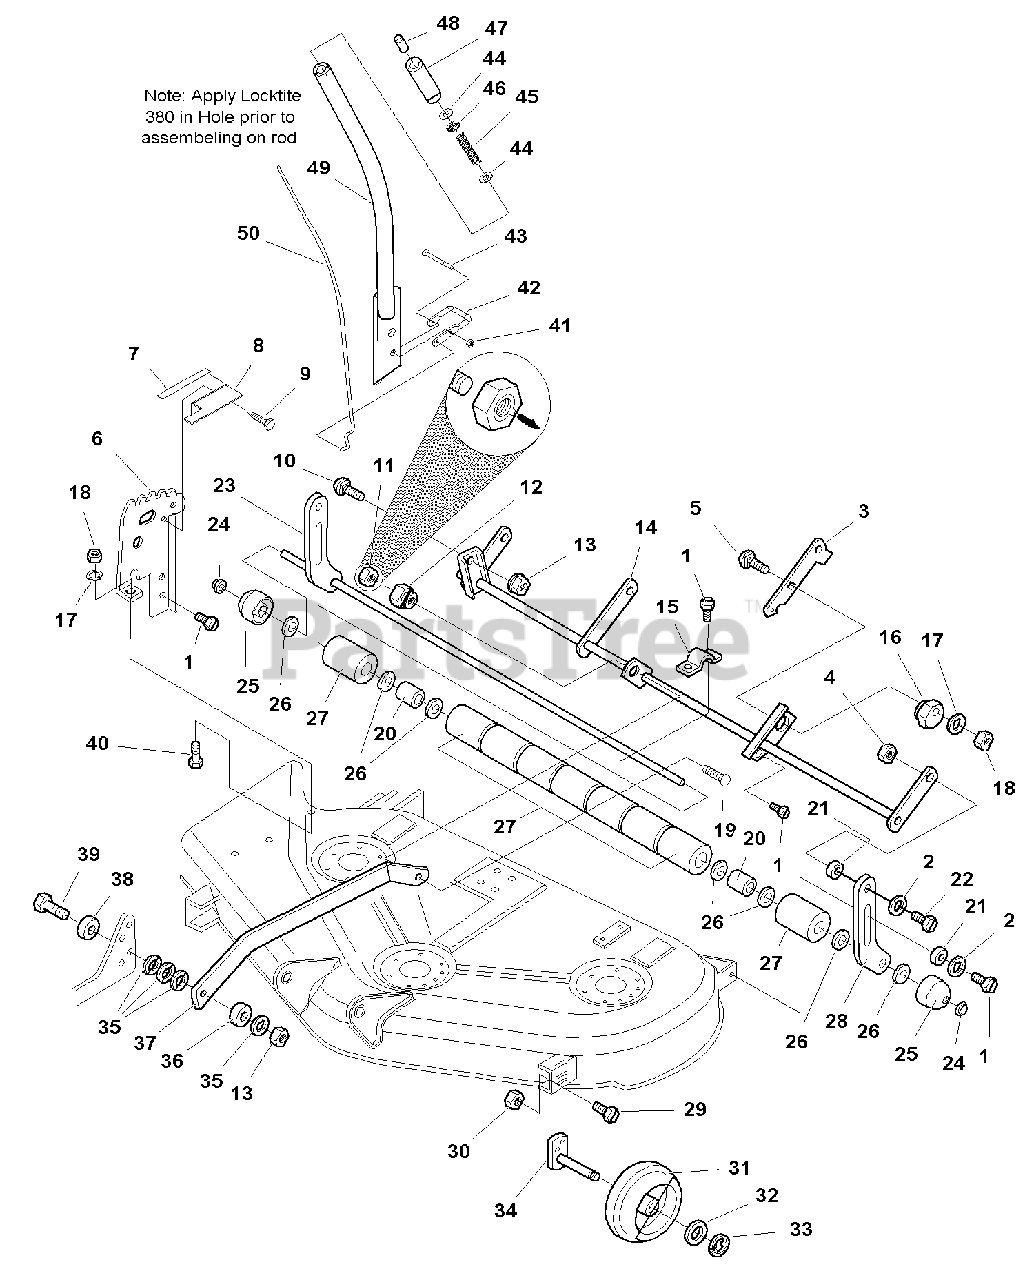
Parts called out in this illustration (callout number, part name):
1	CAPSCREW, Taptite Hex Washer Head, 5/16-18 x 1
2	WASHER, 5/16
3	ARM ASSEMBLY
4	NUT, Hex Lock, 5/16-18
5	CARRIAGE BOLT, 5/16-18 x 1-1/4
6	QUADRANT 44"
7	DECAL, Height of Cut
8	BRACKET, Decal
9	CAPSCREW, Hex Head, Taptite, 5/16-18 x 1/2
10	CARRIAGE BOLT, 3/8-16 x 1
11	* NUT, Hex Lock, Alum Insert, 3/8
12	NUT, Hex Adjusting, .99 DIA .687
13	NUT, Hex Lock, 3/8-16
14	ARM ASSEMBLY, Rocker
15	STRAP
17	WASHER, 5/16
18	NUT, Hex, Flange Collar Lock, 5/16-18
19	CARRIAGE BOLT, 3/8-16 x 1-1/2
20	SPACER, 1-1/4 x 5/8
22	CAPSCREW, Hex Head, 5/16-18 x 1
23	SHAFT ASSEMBLY
24	PUSHNUT, 5/8
25	ROLLER, End
26	WASHER, 5/8
28	BAR, Roller, Support
29	CAPSCREW, Hex Head, 1/4-20 x 3/4
30	NUT, Flange Lock, 1/4-20
31	WHEEL, Gauge
32	WASHER, 1/2
33	E-RING, 1/2
34	ARM ASSEMBLY
35	WASHER, 3/8
39	CAPSCREW, Hex Head, 3/8-16 x 2
40	CAPSCREW, Hex Head, 5/16-18 x 3/4
41	NUT, Hex Lock ESNA, 1/4-20
43	CAPSCREW, Hex Head, 1/4-20 x 2-1/4
44	WASHER
45	SPRING, Compression
46	PUSH NUT, 1/4" Thread
47	GRIP, Lift Lever
49	HANDLE ASSEMBLY
